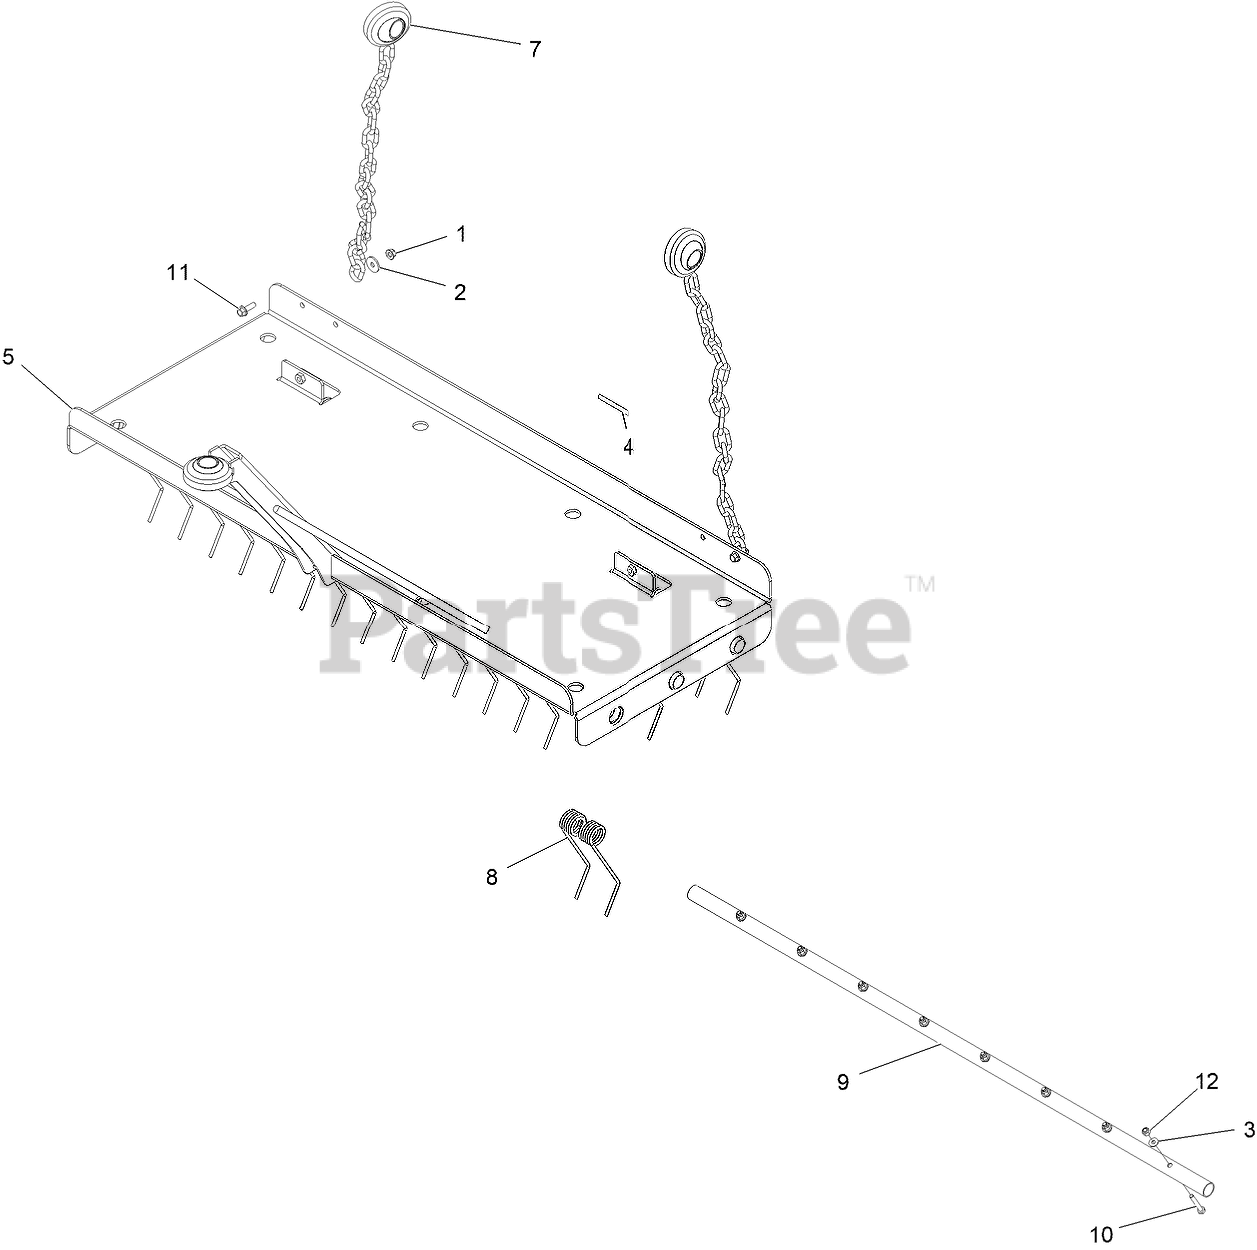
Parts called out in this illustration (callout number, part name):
1	NUT-HF, NI
2	WASHER-FLAT
4	DECAL-WARNING
5	PLATFORM-RAKE
7	RAKE BALL SOCKET AND CHAI
8	SPRING TINE\NGG187DT-NB
9	RAKE TUBE
10	SCREW-HH
11	SCREW-HH
12	NUT-LOCK, NI
